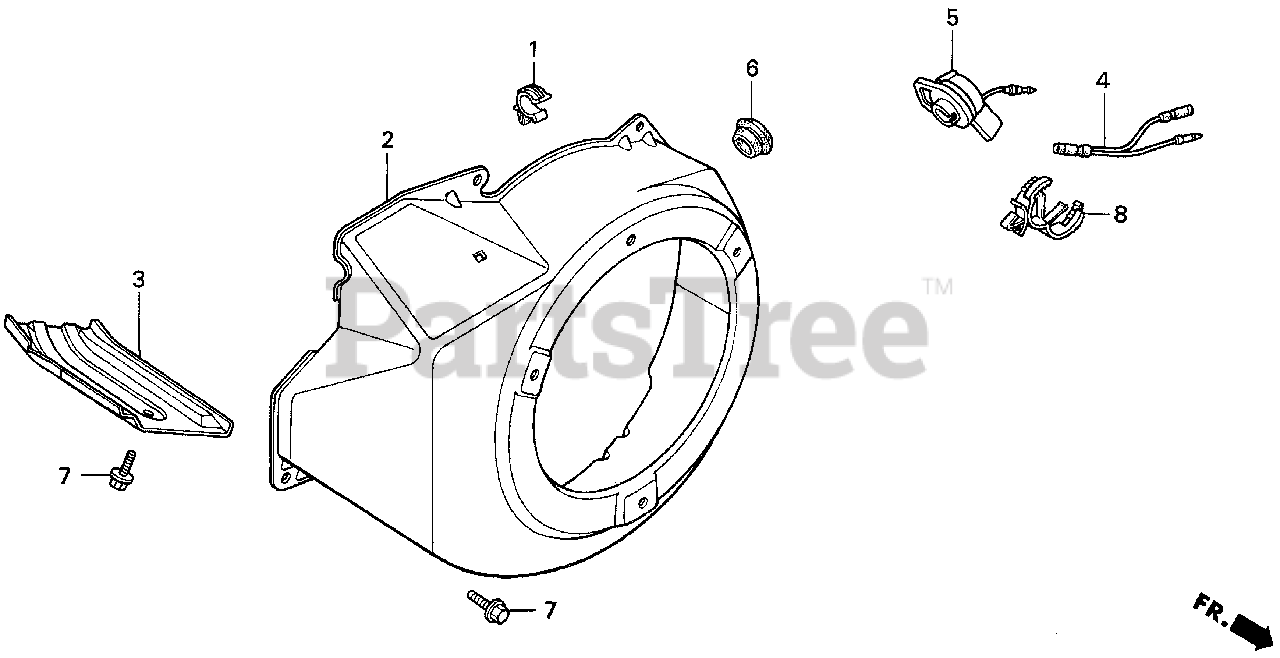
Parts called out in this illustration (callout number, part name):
1	CLIP, TUBE
2	COVER, FAN *R8* (BRIGHT RED)
2	COVER, FAN *NH1* (BLACK)
2	COVER, FAN *NH246* (LOOSY GRAY)
3	SHROUD
4	SUB-HARNESS
5	SWITCH ASSY., ENGINE STOP
7	BOLT, FLANGE (6X12) (CT200)
8	CLIP, WIRE HARNESS
